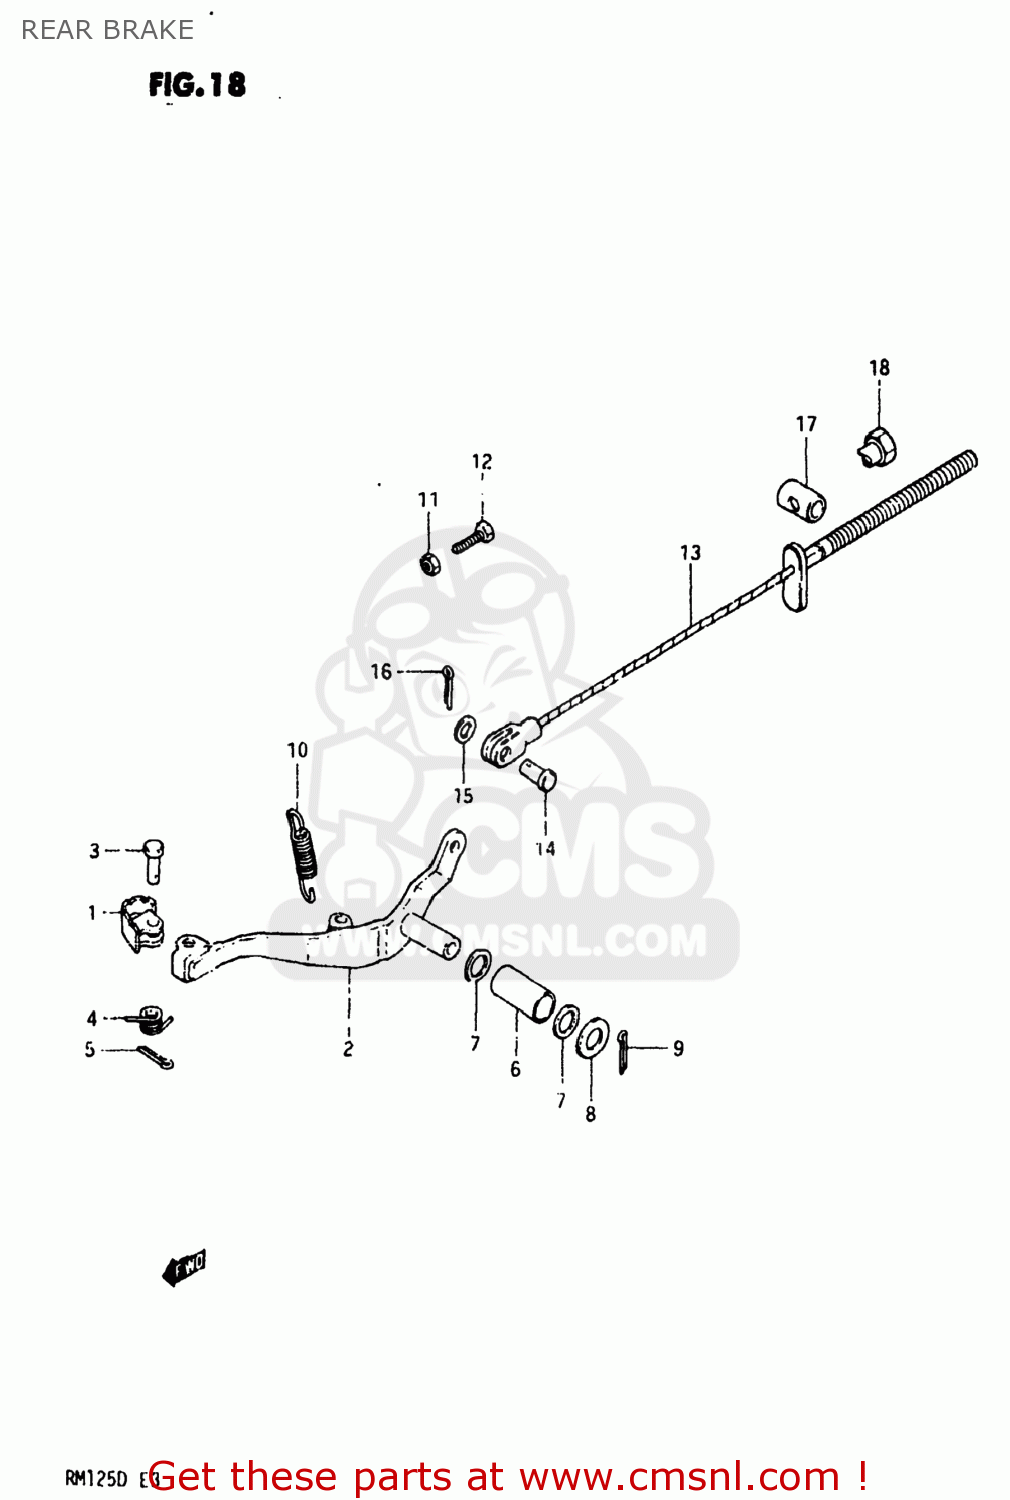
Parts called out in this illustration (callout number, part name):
1	PEDAL,BRAKE
2	ARM,BRAKE PEDAL
3	PIN
4	SPRING
5	PIN
6	BUSHING
7	O RING(D:2.2,ID:11.8)
8	WASHER
9	PIN 30X20
10	SPRING
11	SCREW(6X23)
12	NUT
13	CABLE,RR BRAKE
14	PIN(L:17.5)
15	WASHER
16	PIN 20X20
17	PIN
18	NUT (6MM)
